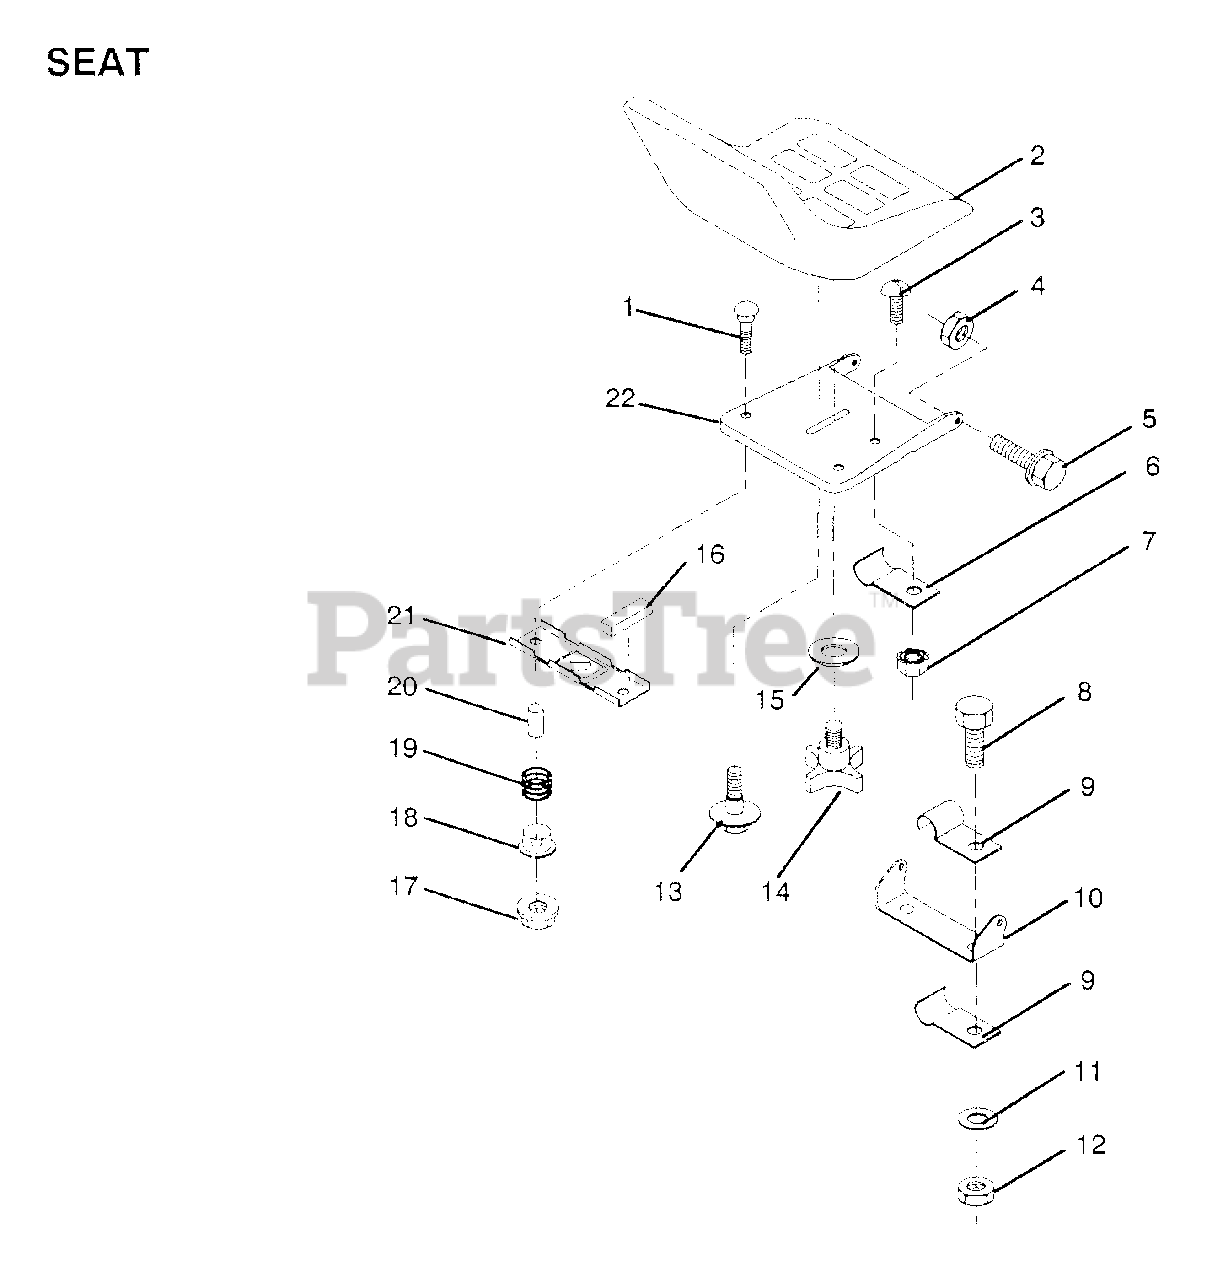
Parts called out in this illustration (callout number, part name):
1	BOLT
7	"NUT,KEPS"
9	"CLIP,INSULATOR"
11	WASHER
13	"BOLT,SHOULDER"
14	"KNOB 1/2"" YT"
15	WASHER
16	STRIP FORM
18	BUSHING
19	SPRING
20	SPACER SPLIT
21	BRKT SWITCH
